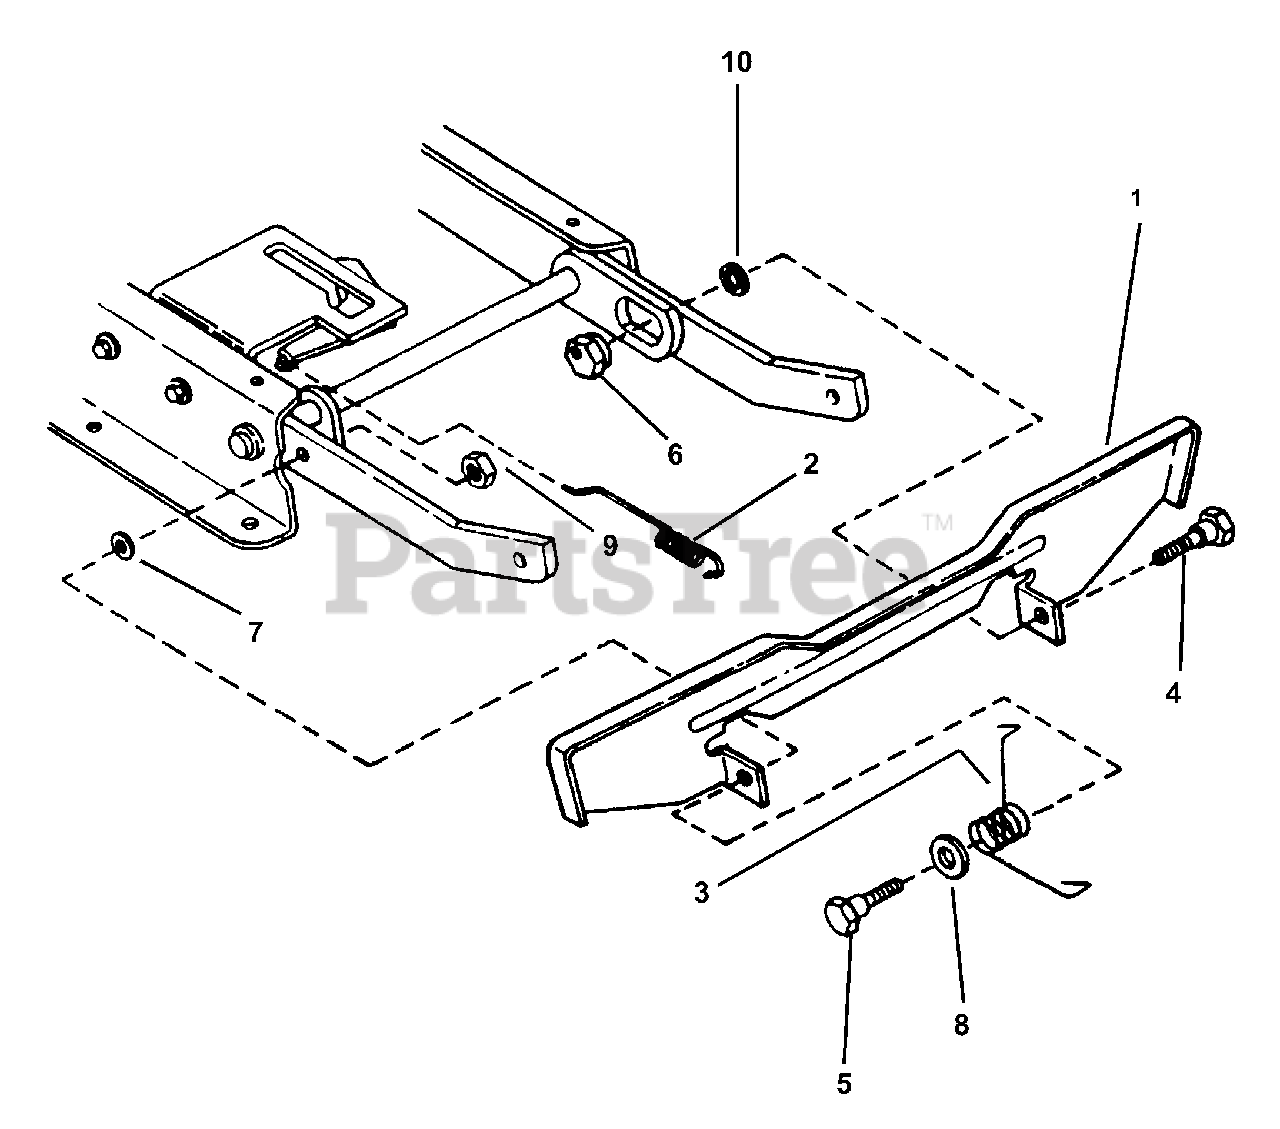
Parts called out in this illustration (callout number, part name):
1	PEDAL, Blade Stop Control
2	SPRING, Latching
3	SPRING, Pedal
4	BOLT, 3/8-24 x 3/4" Shoulder
5	BOLT, 3/8-24 x 9/16" Shoulder
6	ECCENTRIC, Leveling
7	WASHER, 3/8" Flat
8	WASHER, 1/2 Flat
9	NUT, 3/8-24 Hex Center Lock
10	WASHER, 3/8 Internal Tooth Lock
